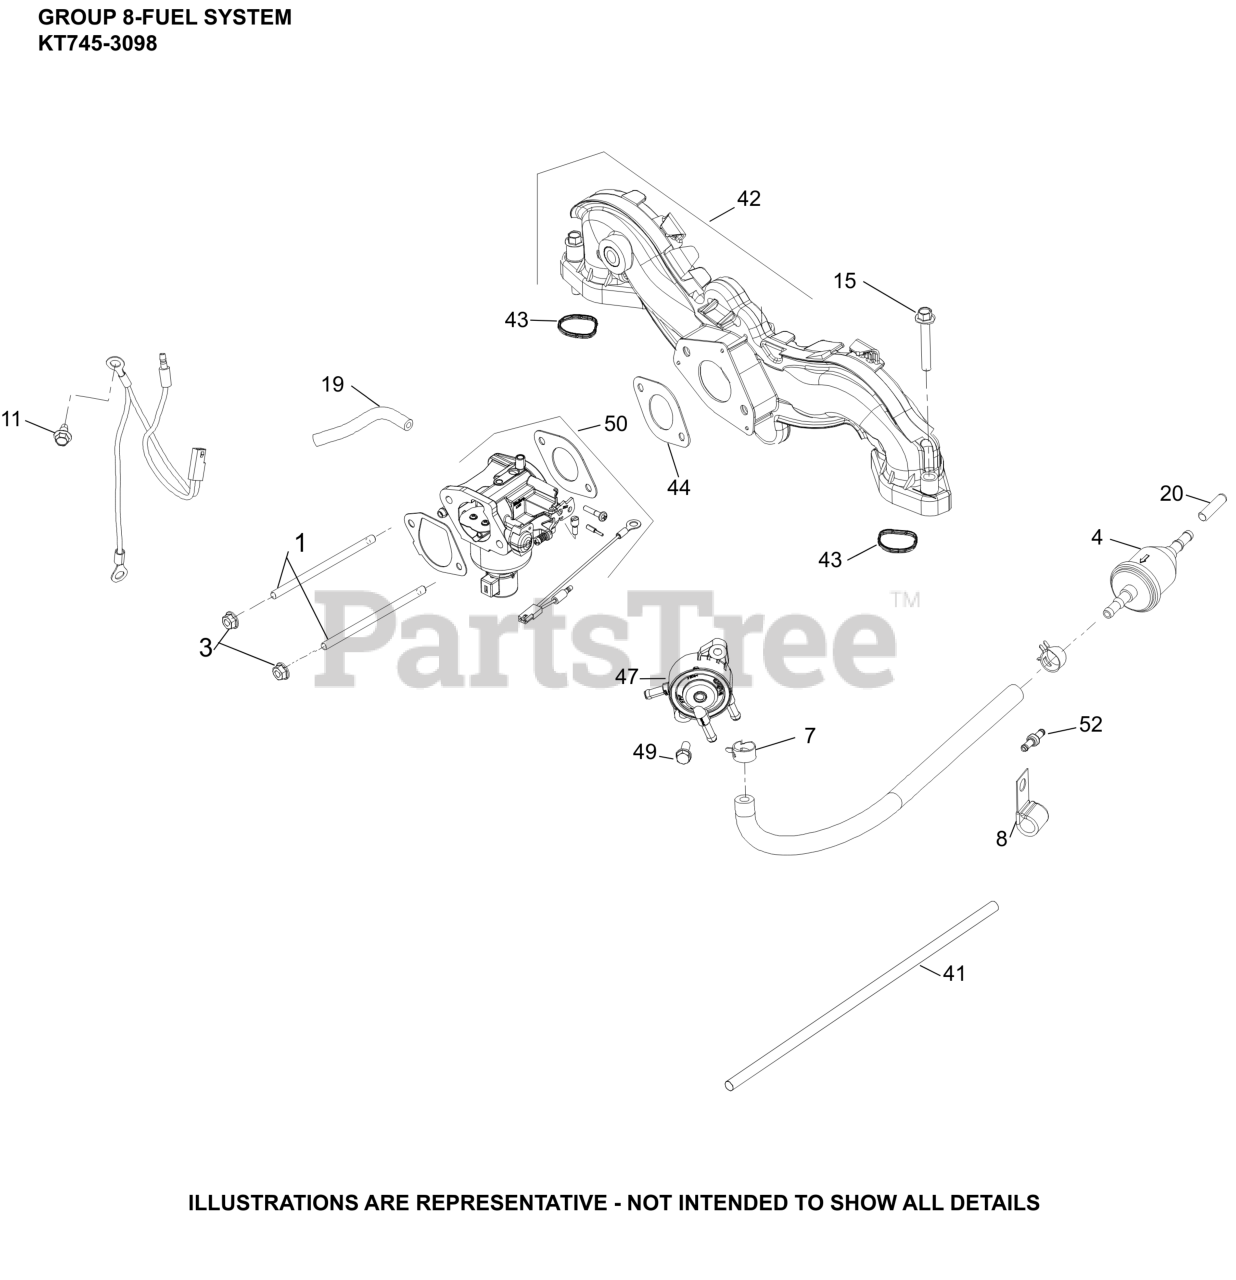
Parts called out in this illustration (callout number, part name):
3	NUT, FLG M6X1.0
4	FILTER,FUEL 51 MICRON (FUEL PUMP)
7	SPRING CLAMP, HOSE
8	CLIP, CABLE (KM)
11	SCREW, THREAD FORMING
15	SCREW, FLG M6X1.0X40
19	HOSE, EVAPORATIVE 20"- (#24326143S)
20	CAP, MASKING
41	SLEEVE, ANTI-ABRASION
42	INTAKE MANIFOLD W/GASKETS
43	O-RING, INTAKE PORT
44	GASKET, CARBURETOR (PIM, CV)
47	PUMP, FUEL (PULSE)
49	SCREW, HEX HEAD
50	KIT, CARBURETOR COMPLETE
52	FITTING, FUEL SYSTEM
NI	KIT,REPAIR OVERHAUL(WALBRO)
NI	KIT,BOWL O-RING(WALBRO)
NI	KIT, HIGH ALT (4000-8000 FT)WALBRO)
NI	KIT,SOLENOID REPAIR(WALBRO)
NI	KIT,REPAIR FLOAT(WALBRO)
